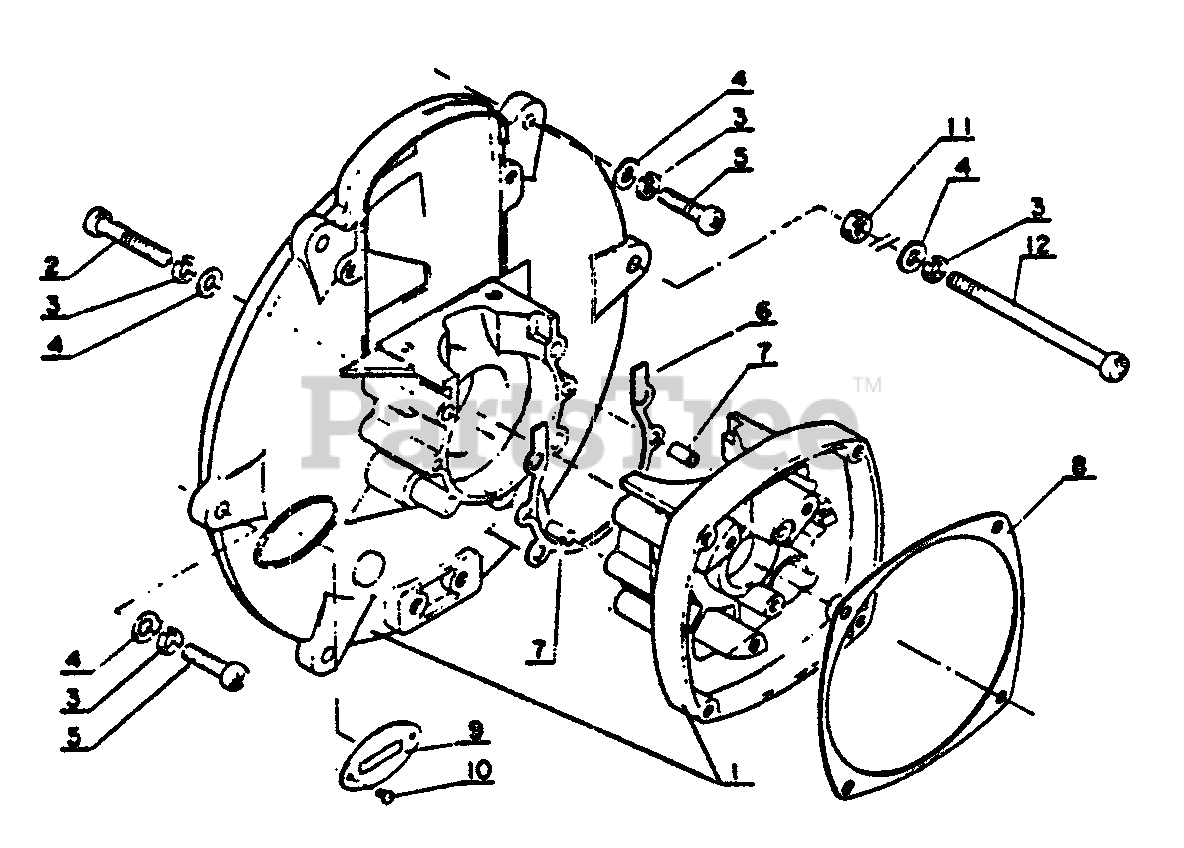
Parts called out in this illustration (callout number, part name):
1	CRANKCASE KIT
2	SCREW 5×28
3	WASHER, SPRING 5
4	WASHER, FLAT 5.5×10×0.8
5	SCREW 5×18
6	GASKET, CRANKCASE
7	PIN, LOCATING 4
8	GASKET, STARTER
9	MODEL PLATE
10	RIVET
11	NUT M5
12	SCREW 5×70
